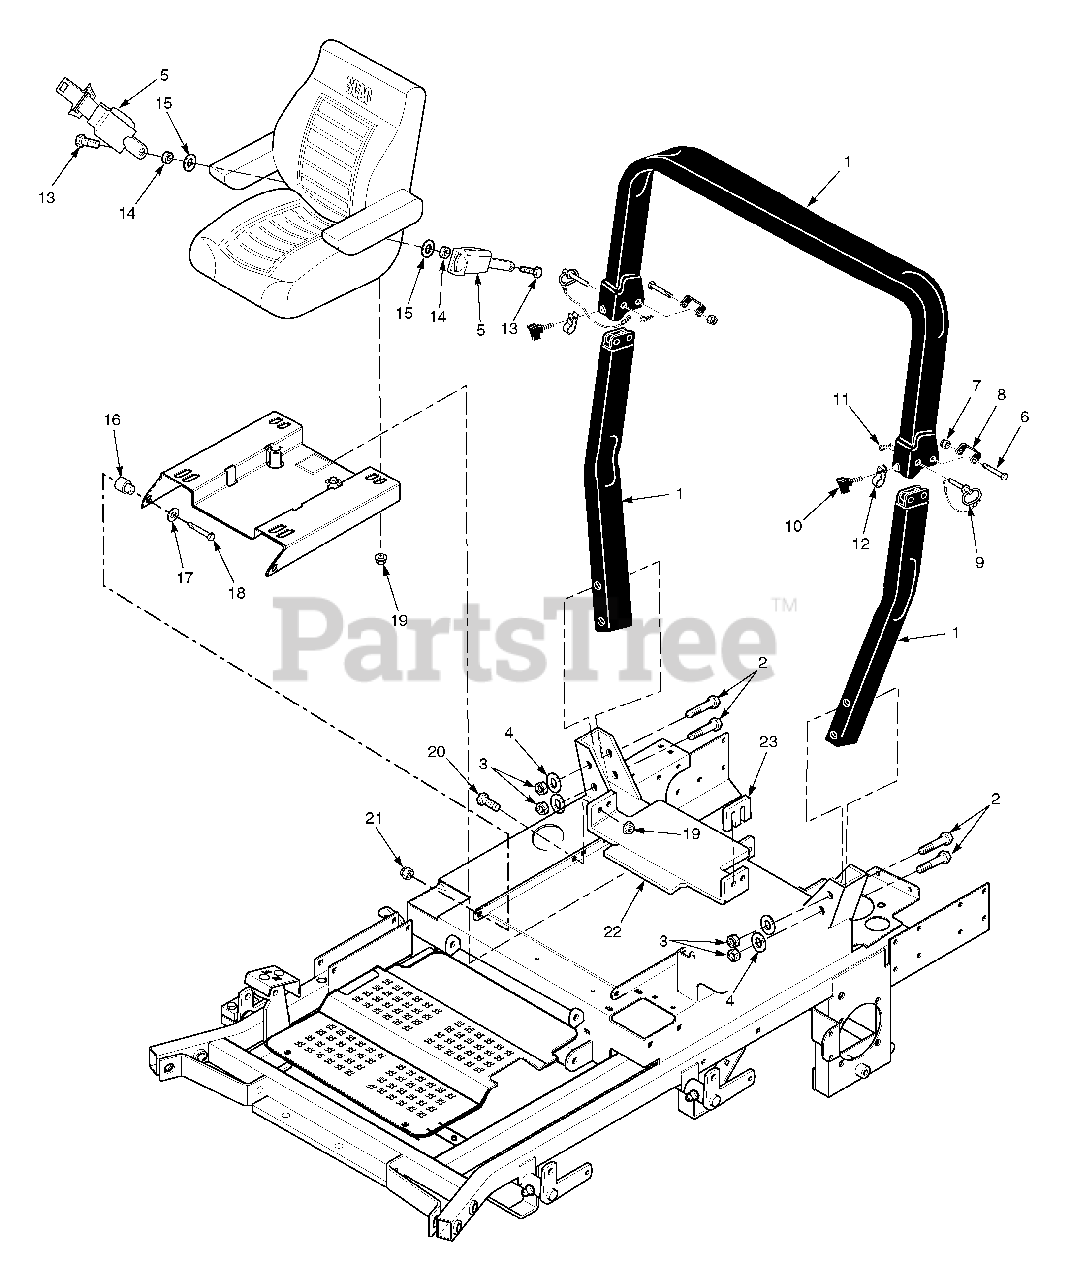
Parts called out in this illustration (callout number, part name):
1	STT, ROPS Acessory
2	Bolt, Hex Head 1/2-13 x 4-1/2"
3	Nut, Center Lock 1/2-13
4	Flatwasher, 1/2-.562 x 1.375 x .109
5	Retractable Seat Belt
6	Bolt, Hex Head 1/2-13 x 3-1/2"
7	Nut, Center Lock 1/2-13
8	Bracket, Stop
9	Pin
10	Thumb Screw, 5/16-18 NC x 3-4"
11	Hair Pin, Cotter
12	Clamp
13	Bolt, Hex Head 7/16-20 x 1"
14	Spacer
15	Flatwasher, 7/16-.500 x 1.25 x .083
16	Sleeve, Seat Base Mounting
17	Flatwasher, 3/8-.391 x .938 x .105
18	Bolt, Hex Head 3/8-16 x 2"
19	Nut, Serrated Flange 5/16-18
20	Bolt, Hex Head 5/16-18 x 1"
21	Nut, Elastic Stop 3/8-16
22	Bracket, Seat Hold Down w/Decal
23	Spacer, Seat Hold Down
